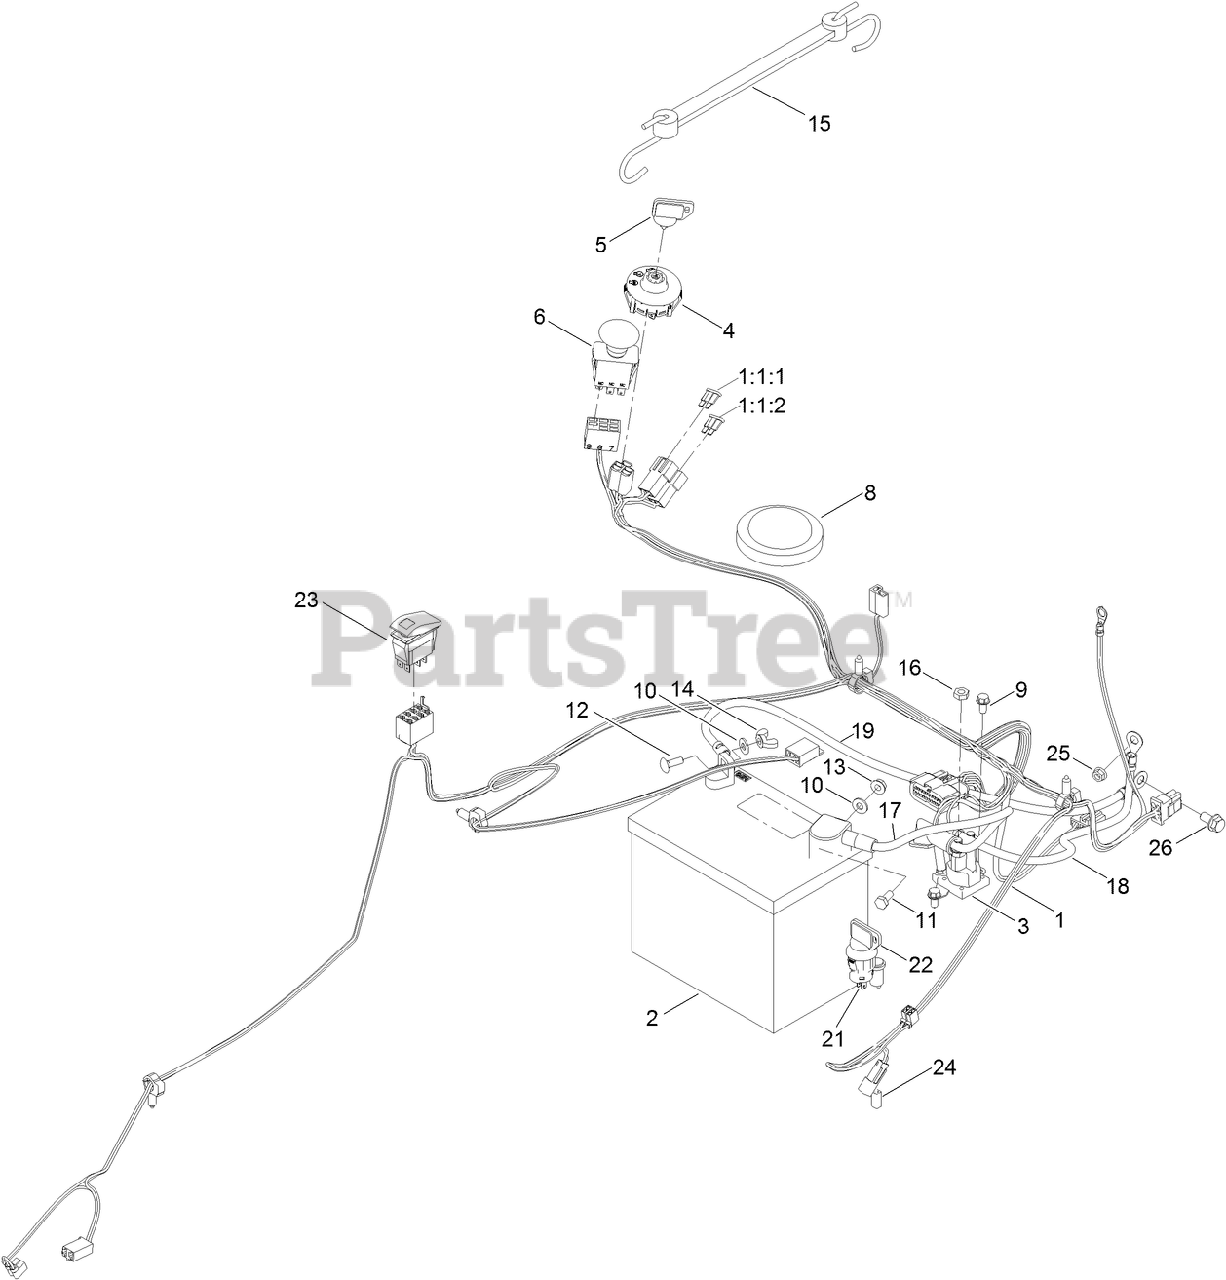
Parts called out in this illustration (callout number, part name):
1	HARNESS-WIRE
1:1	HARNESS-WIRE
1:1:1	FUSE-BLADE, 30 AMP
1:1:2	FUSE-BLADE, 25 AMP
2	BATTERY
3	SOLENOID
4	SWITCH-IGNITION
5	KEY-IGNITION
6	SWITCH-PTO, ON-ON
8	SWITCH-SEAT
9	SCREW-HWH
10	WASHER-FLAT
11	SCREW-HH
12	BOLT-CARR
13	NUT-HF
14	NUT-WING
15	HOLDDOWN-BATTERY
16	NUT-JAM
17	CABLE-BATTERY, RED
18	CABLE-BATTERY, POSITIVE
19	CABLE-BATTERY, BLACK
21	SWITCH-MOMENTARY, N.O.
22	KEY-TORO
23	SWITCH-ROCKER, (ON)-OFF-(ON)
24	LIGHT-INDICATOR
25	NUT-HF
26	SCREW-HHF
